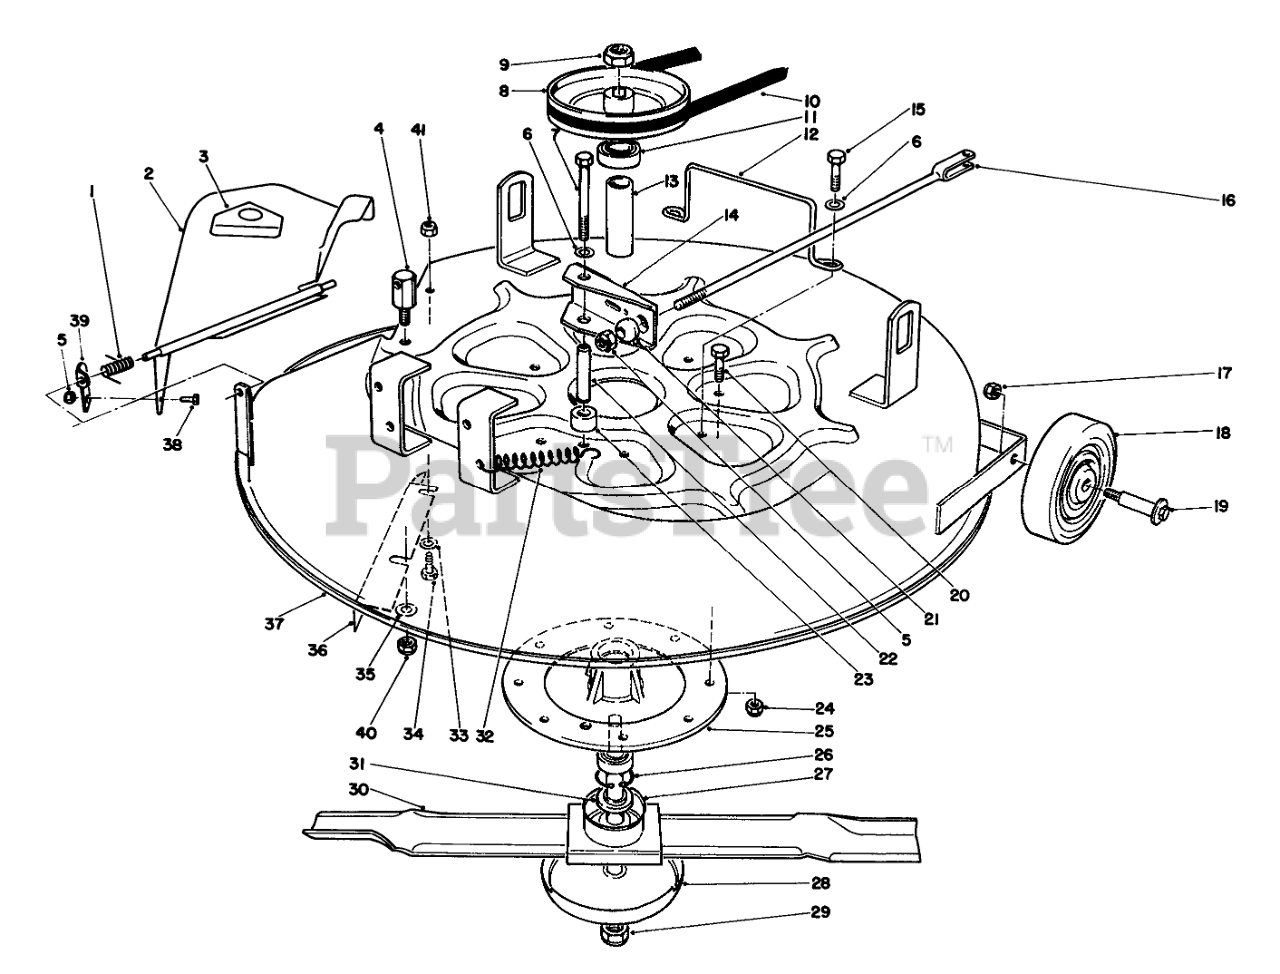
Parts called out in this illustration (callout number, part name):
1	SPRING
2	Deflector (Incl. Ref. #3)
3	DECAL-DANGER
4	POST-PIVOT
5	NUT-LOCK, NI
6	WASHER-PLAIN
7	SCREW-HH
8	DECK PULLEY
9	NUT-LOCK, NI
10	V-Belt
11	BEARING-BALL
12	DECK BELT GUIDE
13	SPACER-BEARING
14	DECK BRAKE ASSEMBLY
15	SCREW-HH
16	DECK BRAKE ROD WA
17	NUT-LOCK, NI
18	WHEEL-DECK
19	BOLT-WHEEL
20	SCREW-HH
21	BALL-SWIVEL, STOP
22	POST-BRAKE MTG
23	SPACER-DECK BRAKE
24	NUT-LOCK, NI
25	CASTING-SPINDLE
26	RING-RETAINING
27	Shaft-Spindle
28	Cup
30	Blade
31	SPINDLE SPACER
32	SPRING-EXTENSION
33	WASHER-FLAT
34	SCREW-HH
35	WASHER-FLAT
36	Baffle
37	Deck
38	SCREW-HH
39	Bracket-Detector
40	NUT-LOCK, NI
41	NUT-HEX
